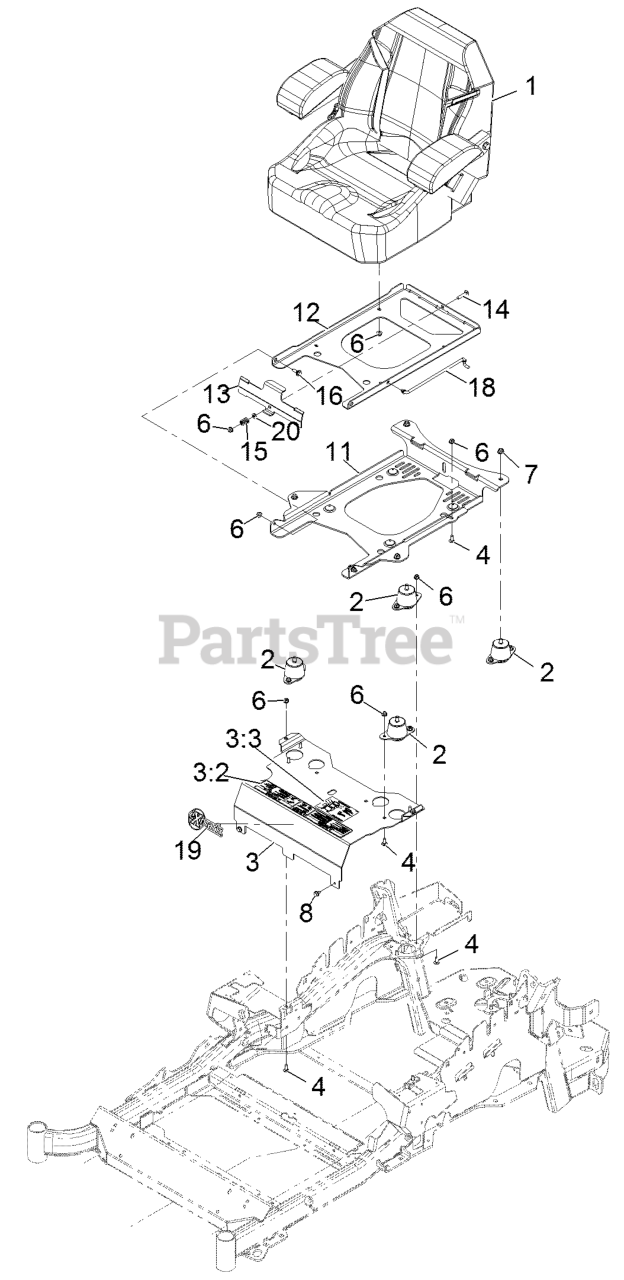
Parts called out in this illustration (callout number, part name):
2	ISOLATOR-SEAT
3	MOUNT-SEAT
3:2	DECAL-CONSOLE
3:3	DECAL-SERVICE AID
4	SCREW-CARR
6	NUT-HF, NI
7	NUT-HF, NI
11	PLATE-TILT, SEAT SUPPORT
12	PLATE-FRAME, SEAT
13	PLATE-LATCH, SEAT
14	BOLT-CARR
15	SPRING-COMPRESSION
16	SCREW-SHOULDER
18	ROD-PROP
20	WASHER-PLAIN
